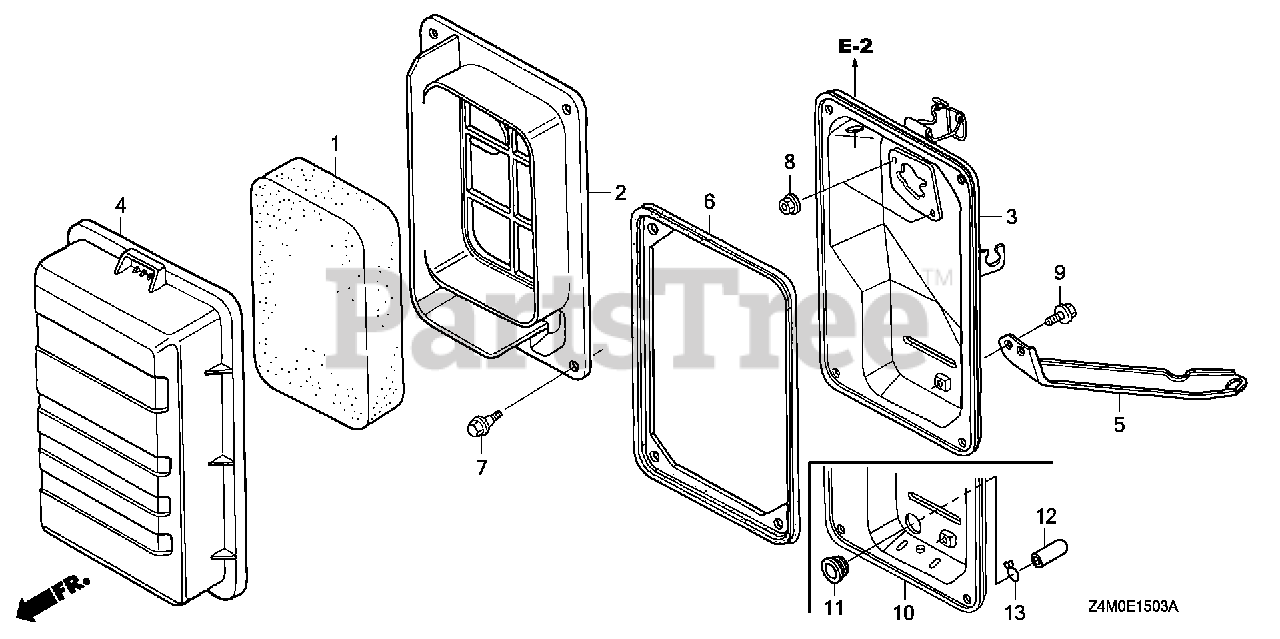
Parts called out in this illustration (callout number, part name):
1	ELEMENT, AIR CLEANER
2	SEPARATOR, AIR CLEANER
3	HOUSING, AIR CLEANER
4	COVER, AIR CLEANER
5	STAY, AIR CLEANER
6	SEAL, AIR CLEANER
7	BOLT, TURN SIGNAL SETTING
8	NUT, FLANGE (6MM)
9	BOLT, FLANGE (6X10)
10	HOUSING, AIR CLEANER
11	GROMMET, AIR CLEANER
12	CAP, SEALING
13	CLIP, TUBE (B10)
